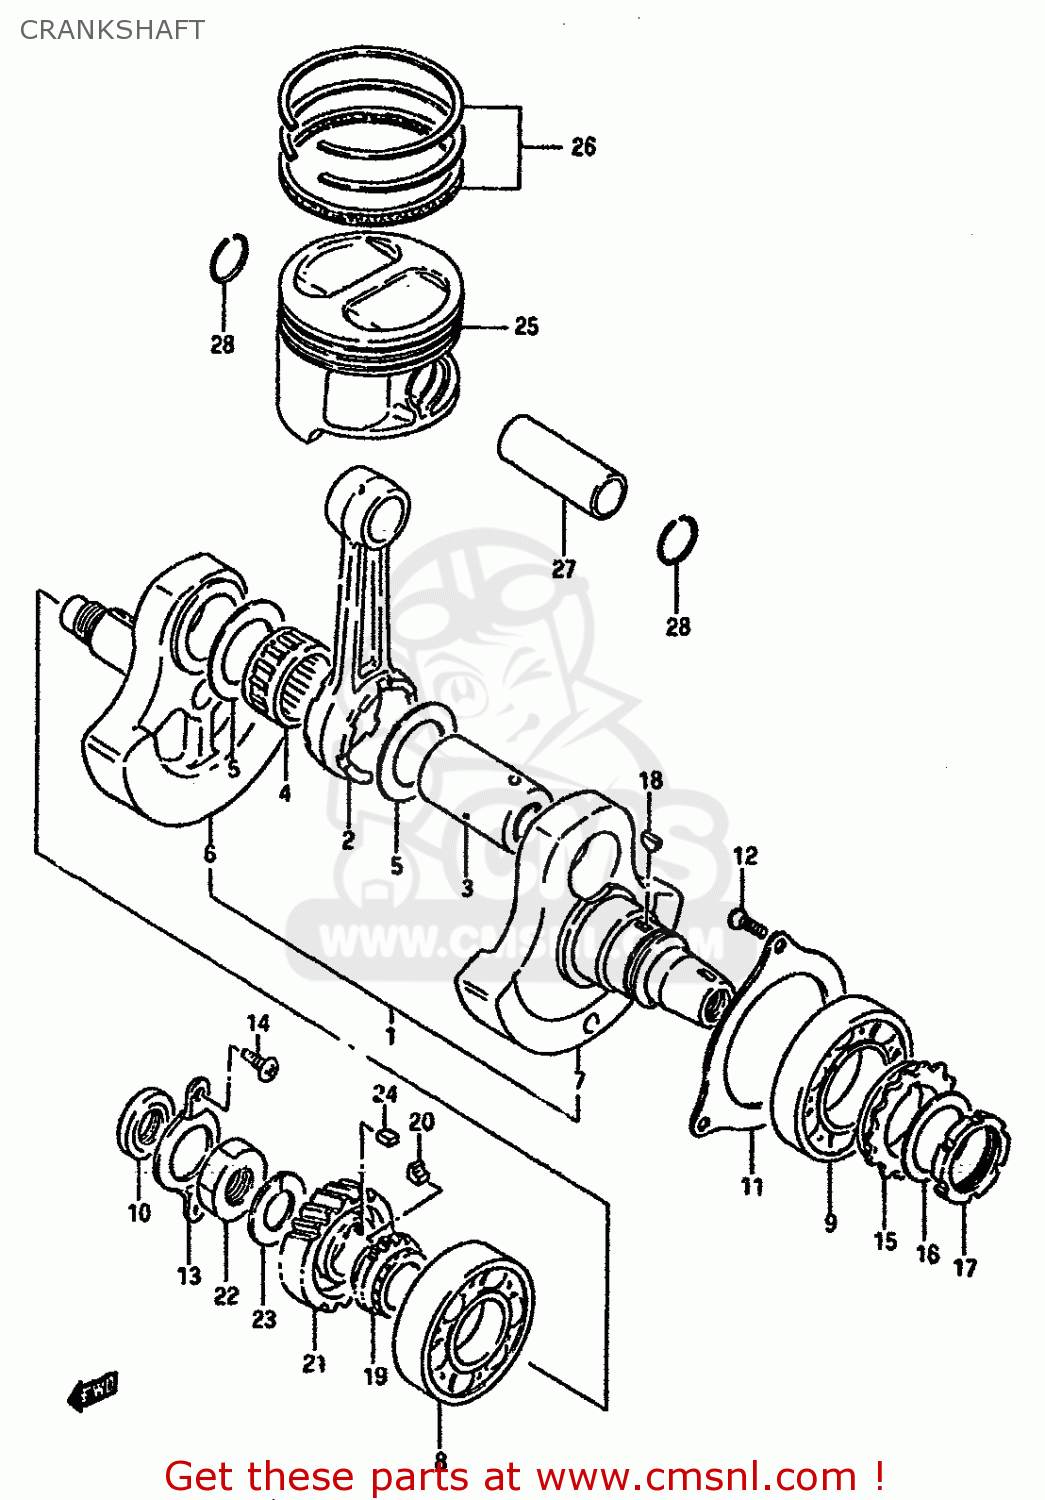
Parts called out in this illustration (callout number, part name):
1	CRANKSHAFT ASSEMBLY
2	CONNECTING ROD
3	PIN,CRANK
4	BEARING
5	WASHER(37X55X1)
6	CRANKSHAFT,RIGHT
7	CRANKSHAFT,LEFT
8	BEARING(35X80X21)
9	BEARING
10	SEAL,OIL(16X30X6)
11	RETAINER,CRANKSHAFT BEARING,L
12	SCREW
13	RETAINER,CRANKSHAFT BEARING,R
14	SCREW
15	SPROCKET,BALANCER DRIVE
16	WASHER
17	NUT,FLYWHEEL
18	KEY
19	SPROCKET,CAM CHAIN DRIVE
20	KEY,SPROCKET
21	GEAR,PRIMARY DRIVE
22	NUT (20MM)
23	WASHER
24	KEY
25	PISTON (OS:0.5)
26	RING SET,PISTON
27	PIN,PISTON
28	CIRCLIP
